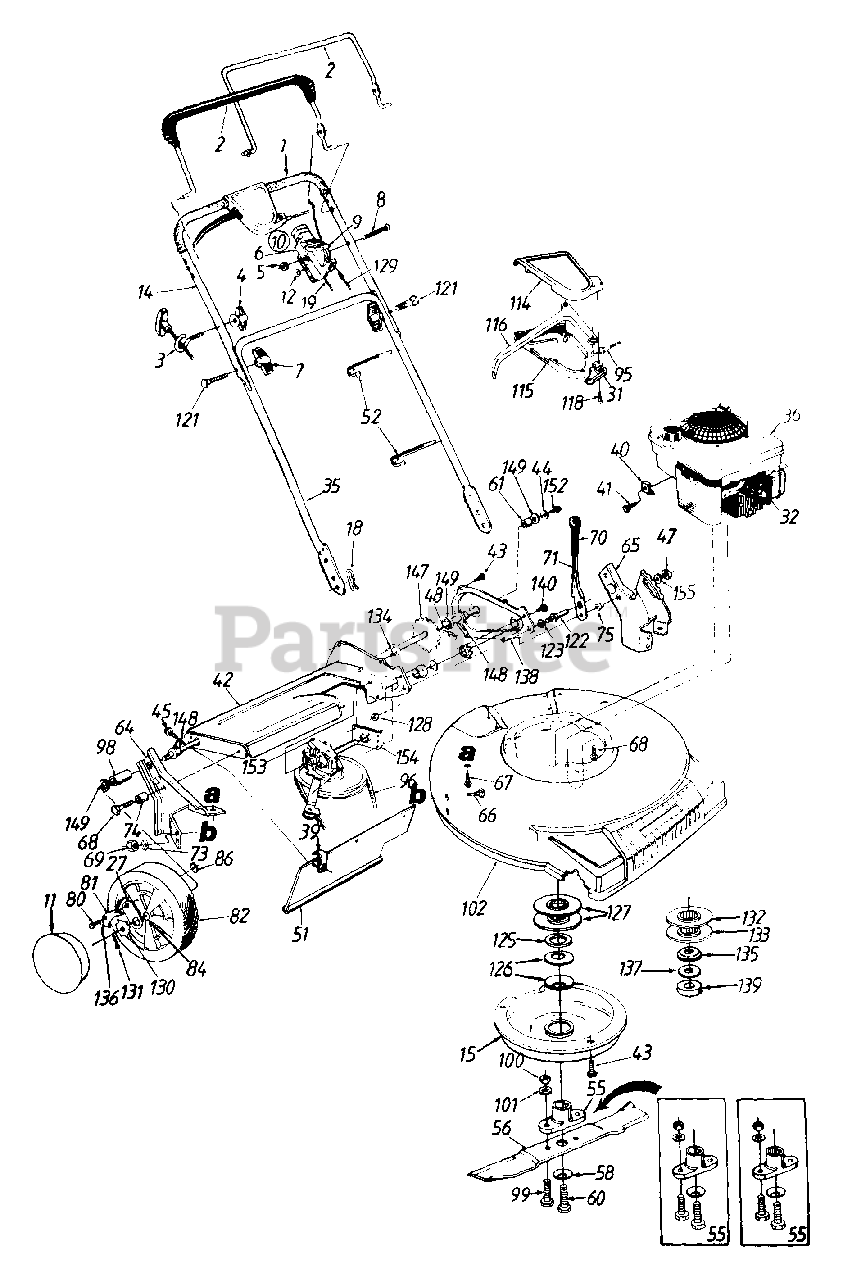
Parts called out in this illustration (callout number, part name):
1	Grip
2	Control Handle w/Plastic
3	Rope Guide
4	Wing Nut 1/4-20 Thd.
5	Hex L-Nut 1/4-20 Thd.
6	Throttle Body
7	Hand Knob
8	Oval C-Sunk Scr.
9	Throttle Lever
10	Throttle Box Comp.
11	Hub Cap
12	Spr. Wash..66" I.D.
19	Throttle Control Wire 55" Lg.
27	Pawl Plate
31	S.P. Control Cover
32	Spark Plug Insulator
36	Engine
39	Clamp
40	Cable Clamp (B&S)
41	Hex Self-Tap Scr. #10-32 x .62" (B&S)
44	Bell-Wash. 1/4" I.D.
45	Hex AB-Tap Scr. 1/4 x .62"
47	Hex Patch L-Nut 3/8-24 Thd.
48	#48 Chain .500" Pitch x 38 Links
51	Rear Flap 3.75" x 17.5" Lg.
52	Cable Tie
55	Blade Adapter Kit
56	21" Mulching Blade
58	Bell-Wash..47" I.D.
60	Hex Bolt 7/16-20 x 2.5"
61	Spacer .513" I.D.
67	Hex B-Tap Scr. 5/16-18
68	Hex TT-Tap Scr. 3/8-16
69	Hex Nut 5/16-18 Thd.
71	Height Adj. Lever
73	Bell-Wash. 5/16" I.D.
74	Spacer .383" I.D.
75	Shld Spacer .5" Dia.
80	Shld. Scr .342" Dia. x .268
81	Pawl
82	Wheel Ass'y Comp.- Rear
84	Sleeve Bearing 1/2" I.D.
86	Weld Top L-Nut 1/4-20 Thd.
95	S.P. Cable - 44" Lg.
96	"V"-Belt
98	Sleeve .526" I.D.
99	Hex Bolt 3/8-24 x 1.0" Lg.
100	Hex Nut 3/8-24 Thd.
101	L-Wash. 3/8" I D.
115	Self-Propelled Control Cover
116	Control Lever
118	Fl-"C"-Sunk Hd. Tap Scr #10 x .75" Lg.
121	Curved Hd. Bolt 5/16-18 x 2" Lg.
122	Shld. Pin 1.43" Lg.
123	L-Wash. 3/8" I.D.
125	Crankshaft Spacer
126	Bell-Wash. 1.01" I.D.
127	Pulley Half
128	Hex Jam Nut 3/8-24 Thd.
129	Control Cable - 39"
130	Ratchet Wheel 1.62" O.D.
131	Cotter Pin 1/8" Dia. x 1"
132	Pulley Half
133	Pulley Half
134	Hex Flange Bearing
135	Spr Wash..89" I.D.
136	Spring - Nylon
137	Fl- Wash..85" I.D.
140	Hex S-Tap Scr. 1/4-20 x .50"
147	Rear Shaft Ass'y. 21.44" Lg.
148	Hex Flange Brg..506" I.D.
149	Fl-Wash..531" I.D. x .930"
152	Hex Bolt 1/4-20 x .62" Lg. (Grade 5)
153	Transmission Comp. (See Breakdown)
155	Fl-Wash..385" I.D. x .87" O.D.
